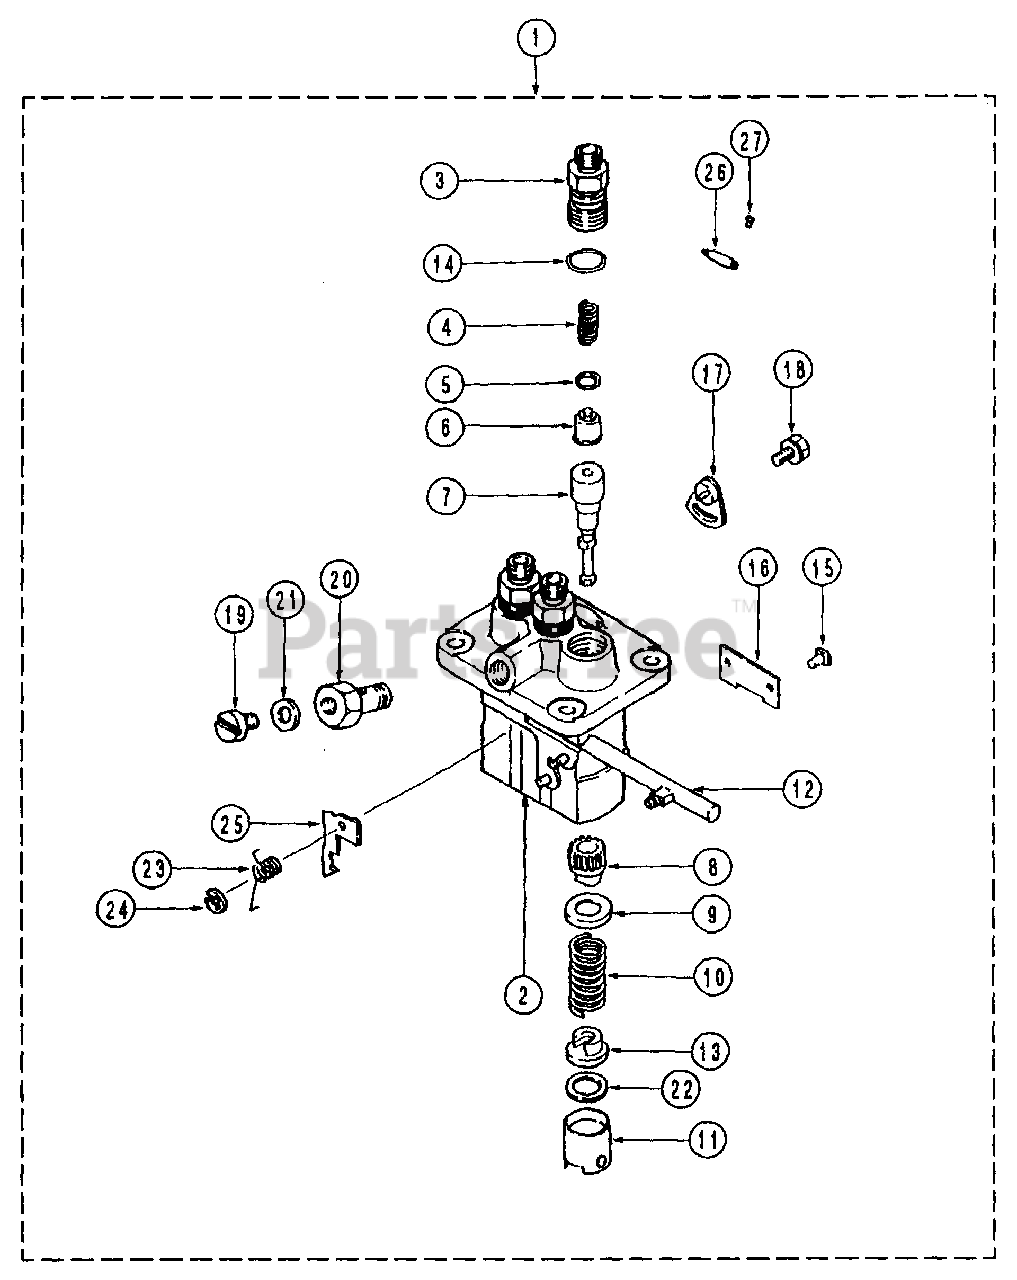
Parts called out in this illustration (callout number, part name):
1	Pump Ass'y, Fuel Inj.
2	Housing Sub Ass'y
3	Holder, Delivery
4	Spring, Delivery V.
5	Gasket, Delivery
6	Valve Sub Ass'y
7	Element Sub Ass'y
8	Sleeve, Control
10	Spring, Plunger
11	Tappet Sub Ass'y
12	Rack Ass'y, Control
13	Seat, Spring Lower
15	Pin, Tappet Guide
17	Plate, Adjusting
18	Bolt, Washer Head
19	Screw, Air Bleeder
20	Screw, Hollow
22	Plate, Tappet Shim
23	Spring, Smoke Set
25	Plate, Smoke Set
